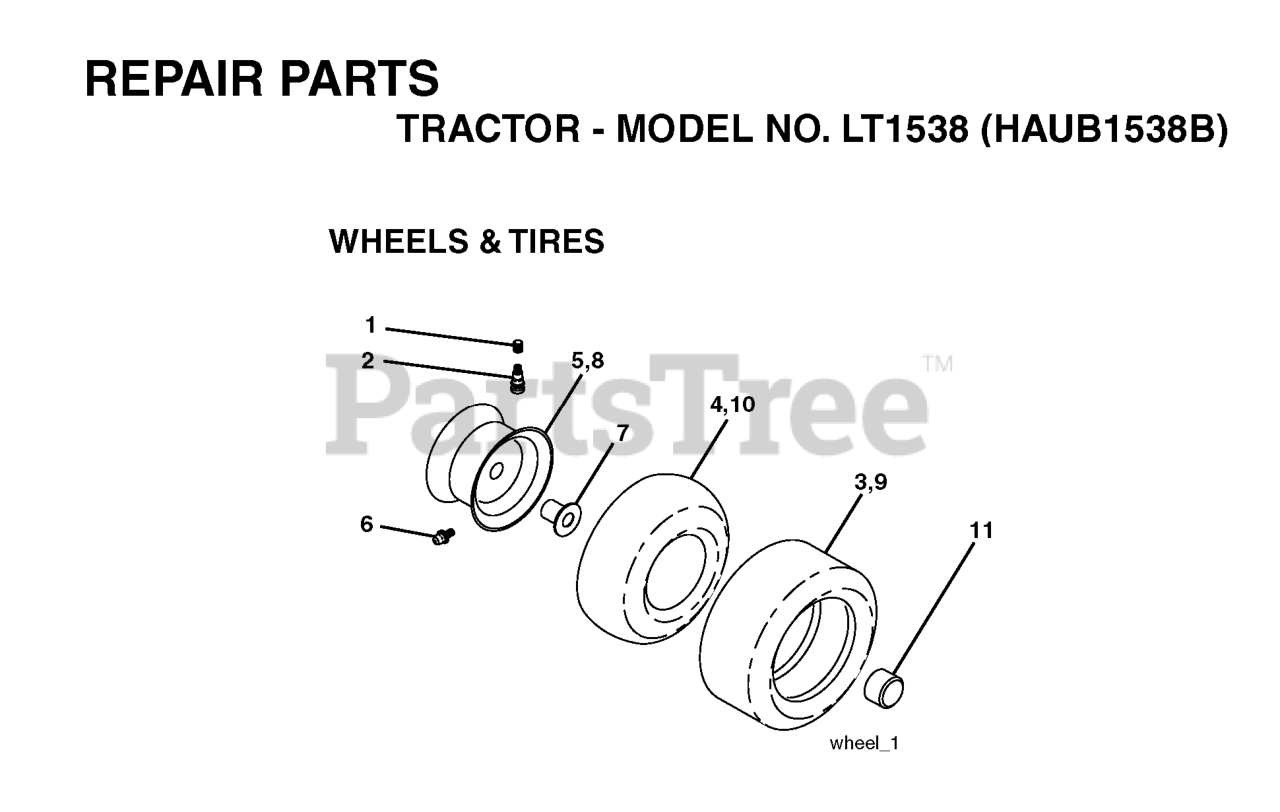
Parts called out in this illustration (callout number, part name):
2	VALVE STEM LT
3	TIRE HEAVY DUTY
4	TUBE.5.3/4.5/6
5	RIM ASM 6" FRONT SILVER
6	FITTING LT
7	BEARING T
8	RIM ASM 8" REAR SILVER
9	TIRE
10	TUBE
11	CAP, AXLE BLK
